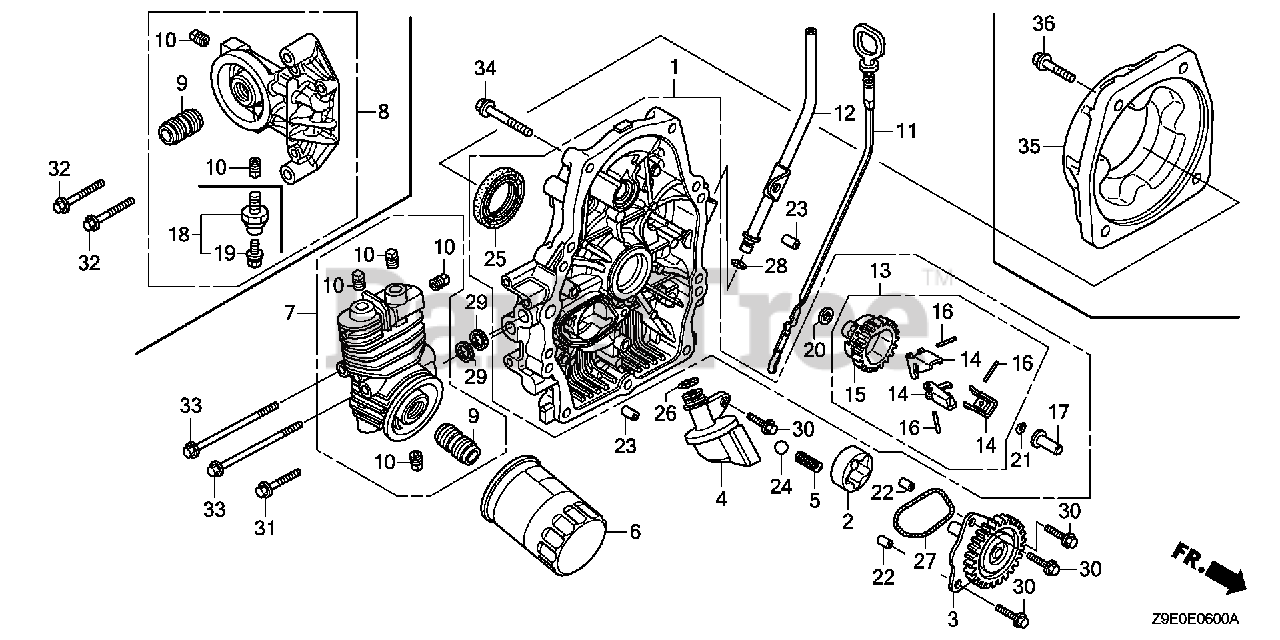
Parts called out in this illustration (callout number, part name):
1	COVER ASSY., CRANKCASE
2	ROTOR, OIL PUMP (OUTER)
3	GEAR, OIL PUMP
4	STRAINER, OIL
5	SPRING, RELIEF VALVE
6	FILTER, OIL (FILTECH TOYO ROKI) (SOLD IN MULTIPLES OF 30)
6	FILTER, OIL (FILTECH TOYO ROKI) (SOLD INDIVIDUALLY)
7	BASE, OIL FILTER
9	HOLDER, OIL FILTER
10	BOLT, SEALING
11	DIPSTICK, OIL
12	PIPE, OIL LEVEL
13	GOVERNOR ASSY.
14	WEIGHT, GOVERNOR
15	HOLDER, GOVERNOR WEIGHT
16	PIN, GOVERNOR WEIGHT
17	SLIDER, GOVERNOR
20	WASHER (6X16)
21	CLIP, GOVERNOR HOLDER
22	PIN, DOWEL (8X10)
23	PIN, DOWEL (8X14)
24	BALL, STEEL (#15) (15/32)
25	OIL SEAL (38X58X9)
26	O-RING (14.8X2.4)
27	O-RING, OIL PUMP
28	O-RING (8.8X1.9)
29	GASKET, OIL PASSAGE
30	BOLT, FLANGE (6X20)
31	BOLT, FLANGE (6X28)
33	BOLT, FLANGE (6X90)
34	BOLT, FLANGE (8X45)
35	COVER, MOUNT CASE
36	BOLT, HEX. (3/8-16UNC)
